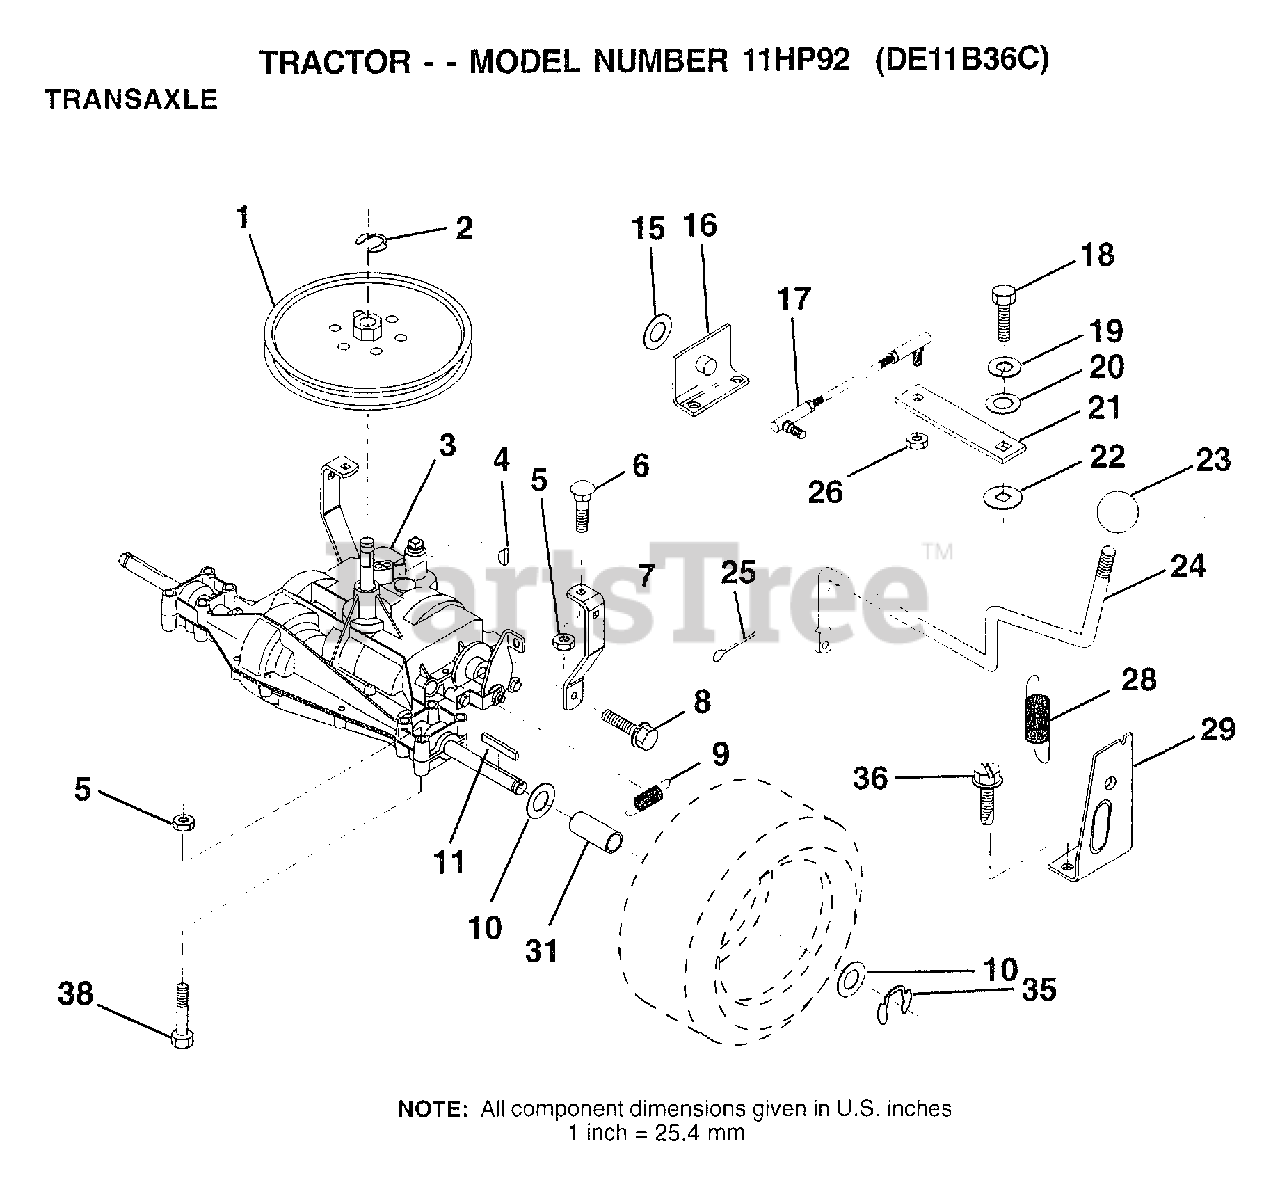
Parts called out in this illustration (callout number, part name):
1	PULLEY
6	BOLT
7	"STRAP,TORQUE"
8	SCREW
9	SPRING.BRAKE.RETU
10	WASHER
11	SQUARE KEY
16	SUPPORT HANDLE SHIFT LH
17	LINK SHIFT
18	BOLT.1/4-28.W/PAT
19	LOCKWASHER
20	WASHER LT
22	WASH-SHFT PLT LT
23	KNOB T (1/2-HOLE)
24	"ROD,SHIFT"
25	PIN COTTER 1/8
26	NUT.LOCK.5/16-24
28	"SPRING,EXT"
29	"SUPT,HDLE RH"
31	SPACER AXLE
35	E-RING LT
36	SCREW
38	BOLT.HEX.FLGHD
